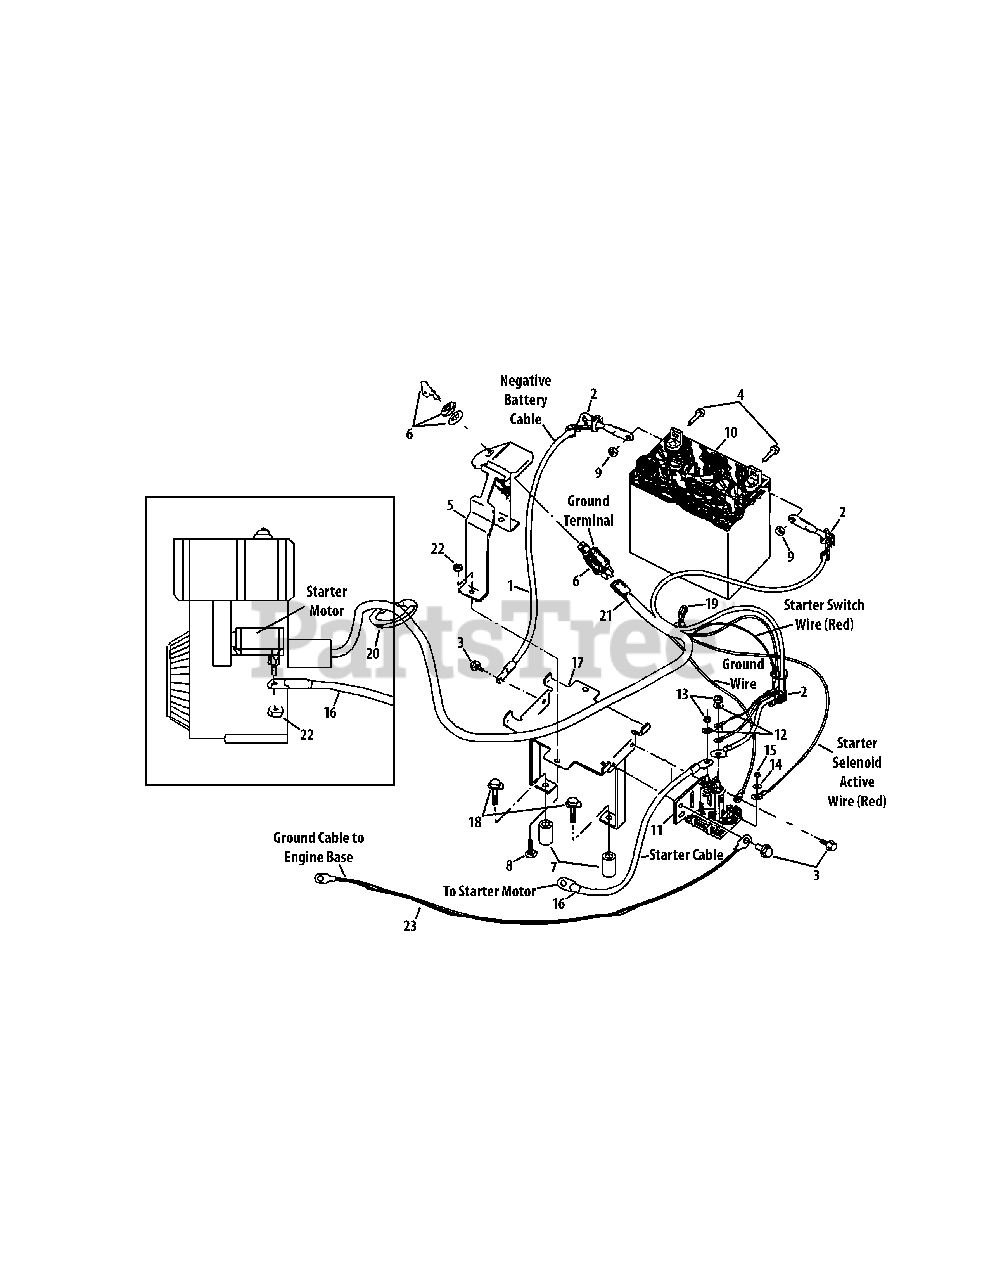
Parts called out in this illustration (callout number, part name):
1	Battery Cable
2	Terminal Insulating Boot
3	TT-Screw, 1/4"-2 x 1/2"
4	Hex Bolt, 1/4"-20 x 5/8"
5	Key Switch w/Decal
6	Key Switch (Incl. 2 Keys)
8	Carriage Bolt, 1/4"-20 x 1-1/4"
9	Hex Nut, 1/4"-20
10	12-Volt Battery
11	Starter Solenoid
12	Lockwasher, 5/16"
13	Hex Nut, 5/16"-24
14	External Tooth Lockwasher
15	Hex Nut, #10-32
16	Battery Cable
17	Battery Bracket
18	Hex Head Screw, 3/8"-16 x 2.75"
19	Plastic Tie
20	Plastic Tie
21	Wire Harness & Connecting Terminal Assembly
22	Flangelock Nut, 1/4"-20
23	Ground Cable
